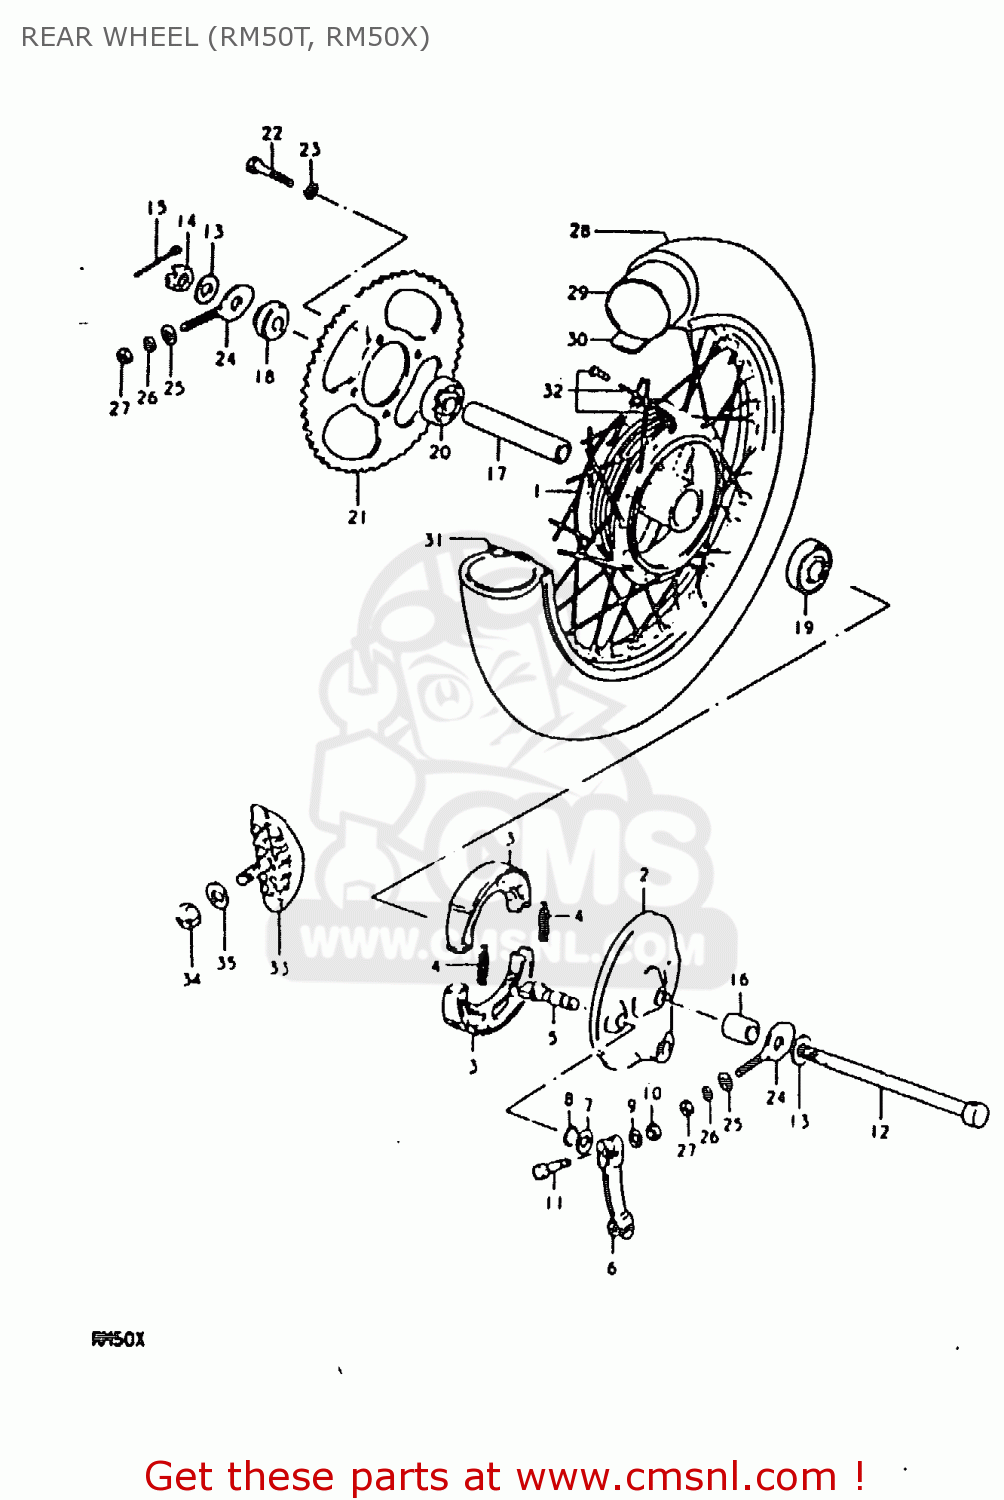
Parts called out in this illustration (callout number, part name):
1	DRUM SET,REAR HUB
2	PANEL,REAR BRAKE ANCHOR
3	SHOE,BRAKE
4	SPRING(L:34)
5	CAM,FRONT BRAKE
6	LEVER,REAR BRAKE CAM
7	WASHER (14.5X22X1.6)
8	O-RING (D:2.4 ID:13.8)
9	WASHER
10	NUT
11	BOLT(6X33)
12	AXLE,REAR
13	WASHER
14	WASHER
15	NUT 12MM
16	COTTER PIN
17	SPACER (12.1X22X27)
18	SPACER(12.6X19X91)
19	BEARING
20	BEARING
21	SPROCKET,RR(NT:42)
22	BOLT
23	LOCK WASHER
24	ADJUSTER,CHAIN,R
25	WASHER
26	LOCK WASHER
27	NUT
28	TIRE
29	TUBE,INNER
30	PROTECTOR,INNER TUBE
31	RIM,REAR WHEEL
32	SPOKE SET,REAR WHEEL
33	STOPPER,BEAD
34	NUT
35	WASHER
